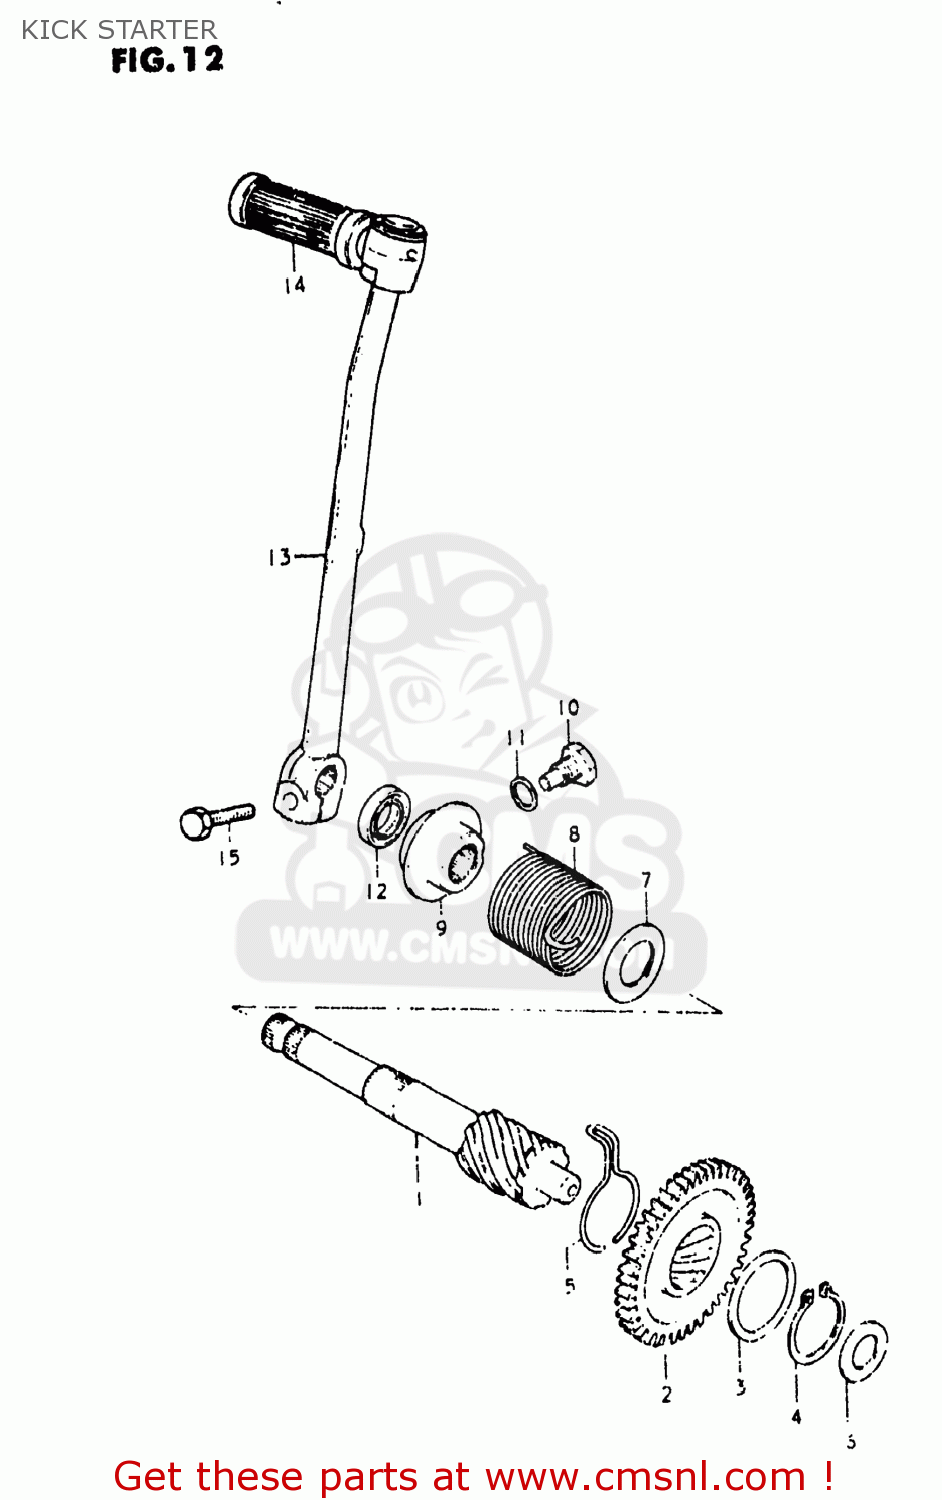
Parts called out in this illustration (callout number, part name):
1	SHAFT,KICK STARTER
2	GEAR,KICK STARTER DRIVE
3	WASHER
4	CIRCLIP
5	RETAINER,SNAP
6	WASHER
7	WASHER(16X30X1)
8	SPRING
9	LIFTER,KICK STARTER
10	BOLT(10X17)
11	GASKET(10X14X3.6) (NAS)
12	SEAL,OIL(14X24X6)
13	LEVER ASSEMBLY,KICK STARTER
14	RUBBER,KICK STARTER PEDAL
15	BOLT
